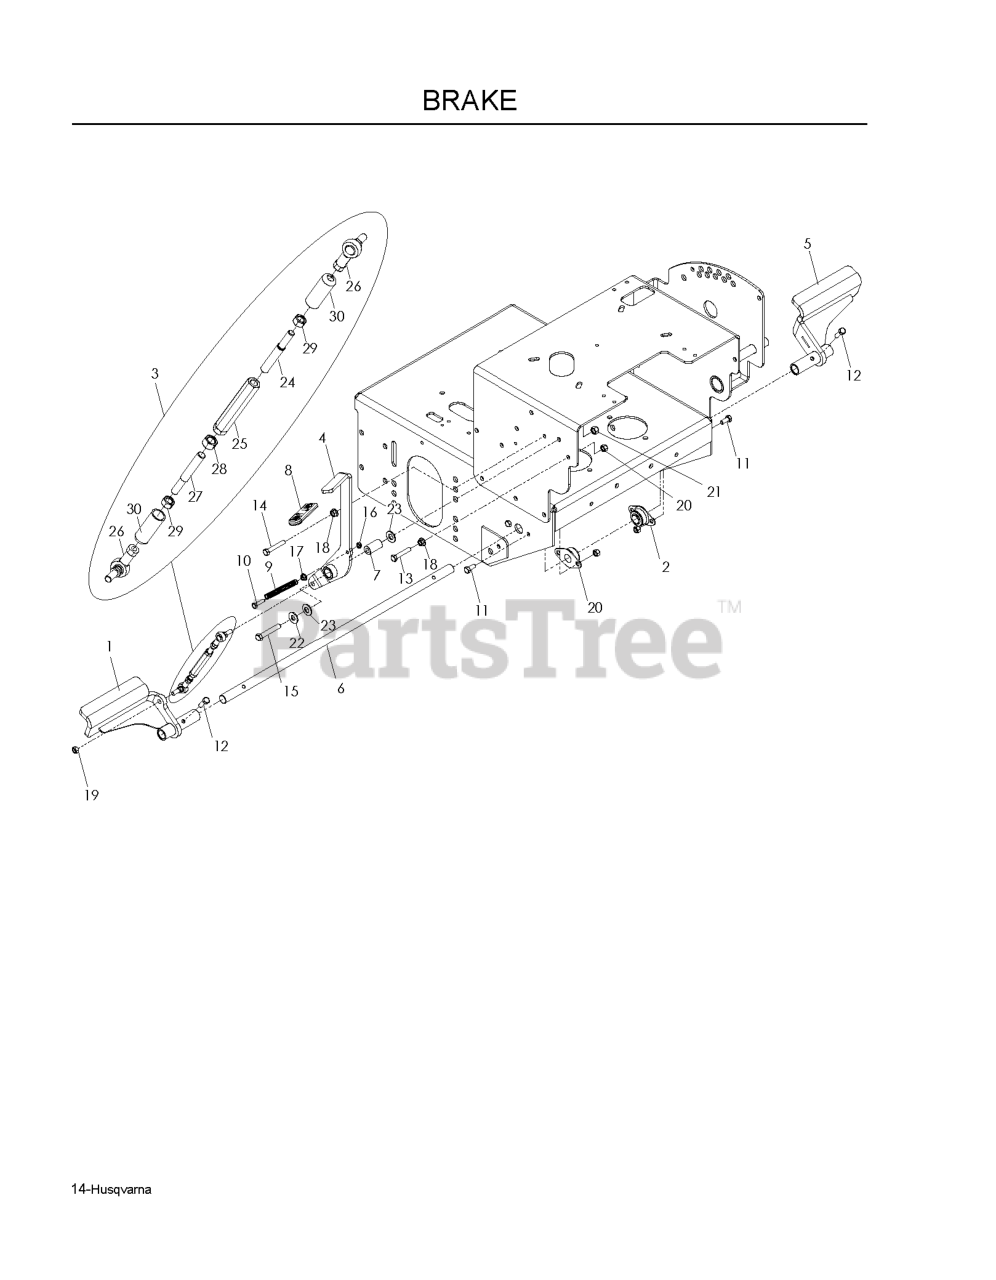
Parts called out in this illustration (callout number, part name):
1	SNUBBER WELDMENT, LT
2	FLANGE BEARING
3	LINKAGE, BRAKE
4	ARM, BRAKE, WELDMENT
5	SNUBBER WELDMENT, RT
6	SHAFT, BRAKE
7	BUSHING, SLEEVE
8	GRIP, PARK BRAKE
10	HCS 1/4 X 1
11	SCREW 5/16C X 1 HEX CAP
12	HCS 5/16C X 1
13	HCS 5/16C X 1 3/4
14	HCS 5/16-18X2
15	HCS 3/8C X 2
16	JAM NUT 1/4C (2 2 PW01)
17	NUT 1/4-20 HEX FLG LK ZD
18	NUT 5/16C WHIZ
19	NUT 5/16C CENTERLOCK
20	NUT 5/16 NYLOC
21	NUT 3/8-16 NYLOC
22	WASHER 3/8 FLAT
23	WASHER, 7/16 DISC SPRING
24	LINKAGE, RH
25	TURNBUCKLE, 3/8
26	SPHERICAL ROD END, RH
27	LINKAGE, LH
